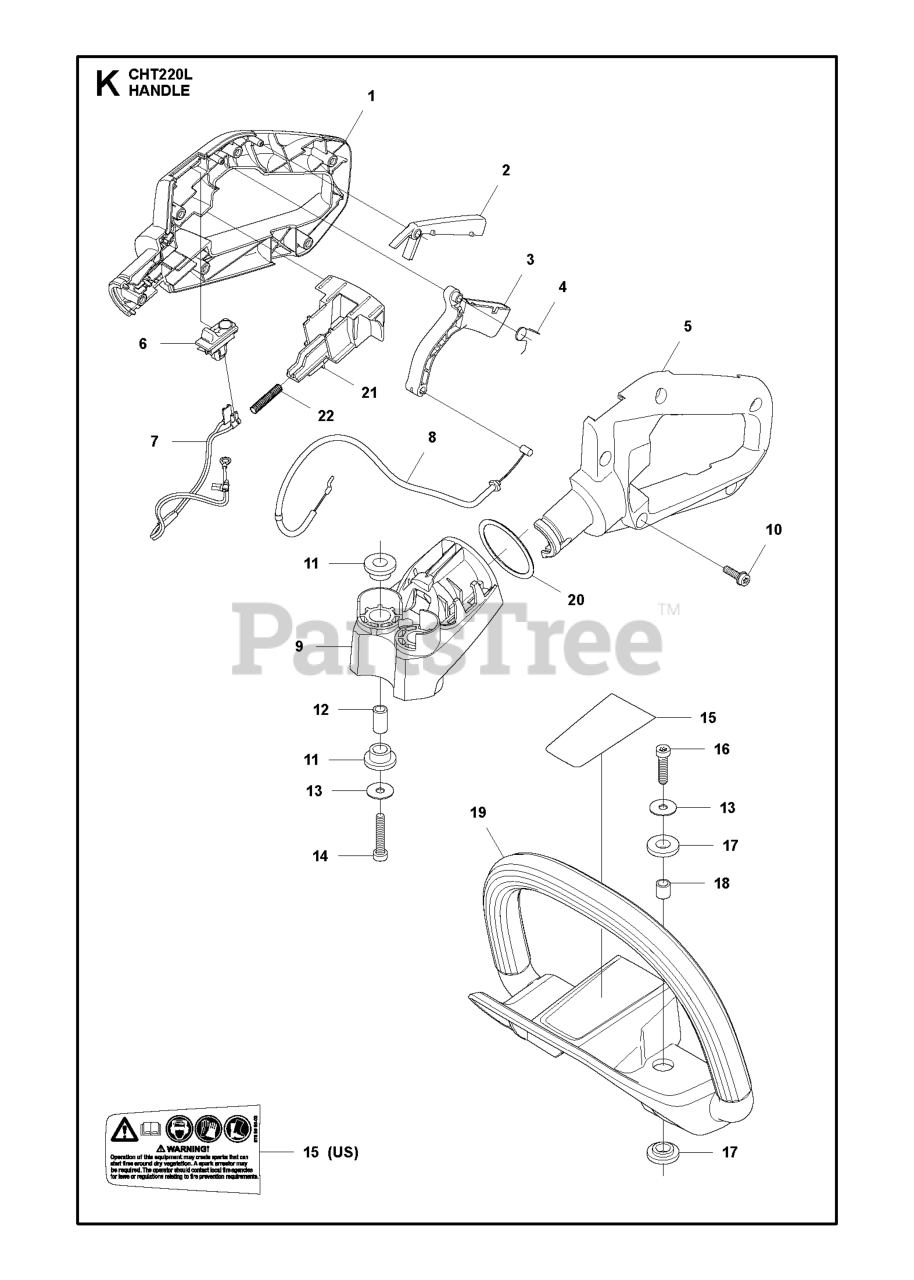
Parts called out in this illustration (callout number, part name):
1	REAR HANDLE
2	THROTTLE LOCKOUT
3	THROTTLE CONTROL
5	REAR HANDLE
6	STOP BUTTON
7	SHORT CIRCUIT CABLE
8	THROTTLE CABLE ASSY
9	HANDLE HOLDER
11	ANTIVIBRATION ELEMENT
17	ANTIVIBRATION ELEMENT
20	O-RING
21	LOCKING BUTTON
22	RECOIL SPRING
